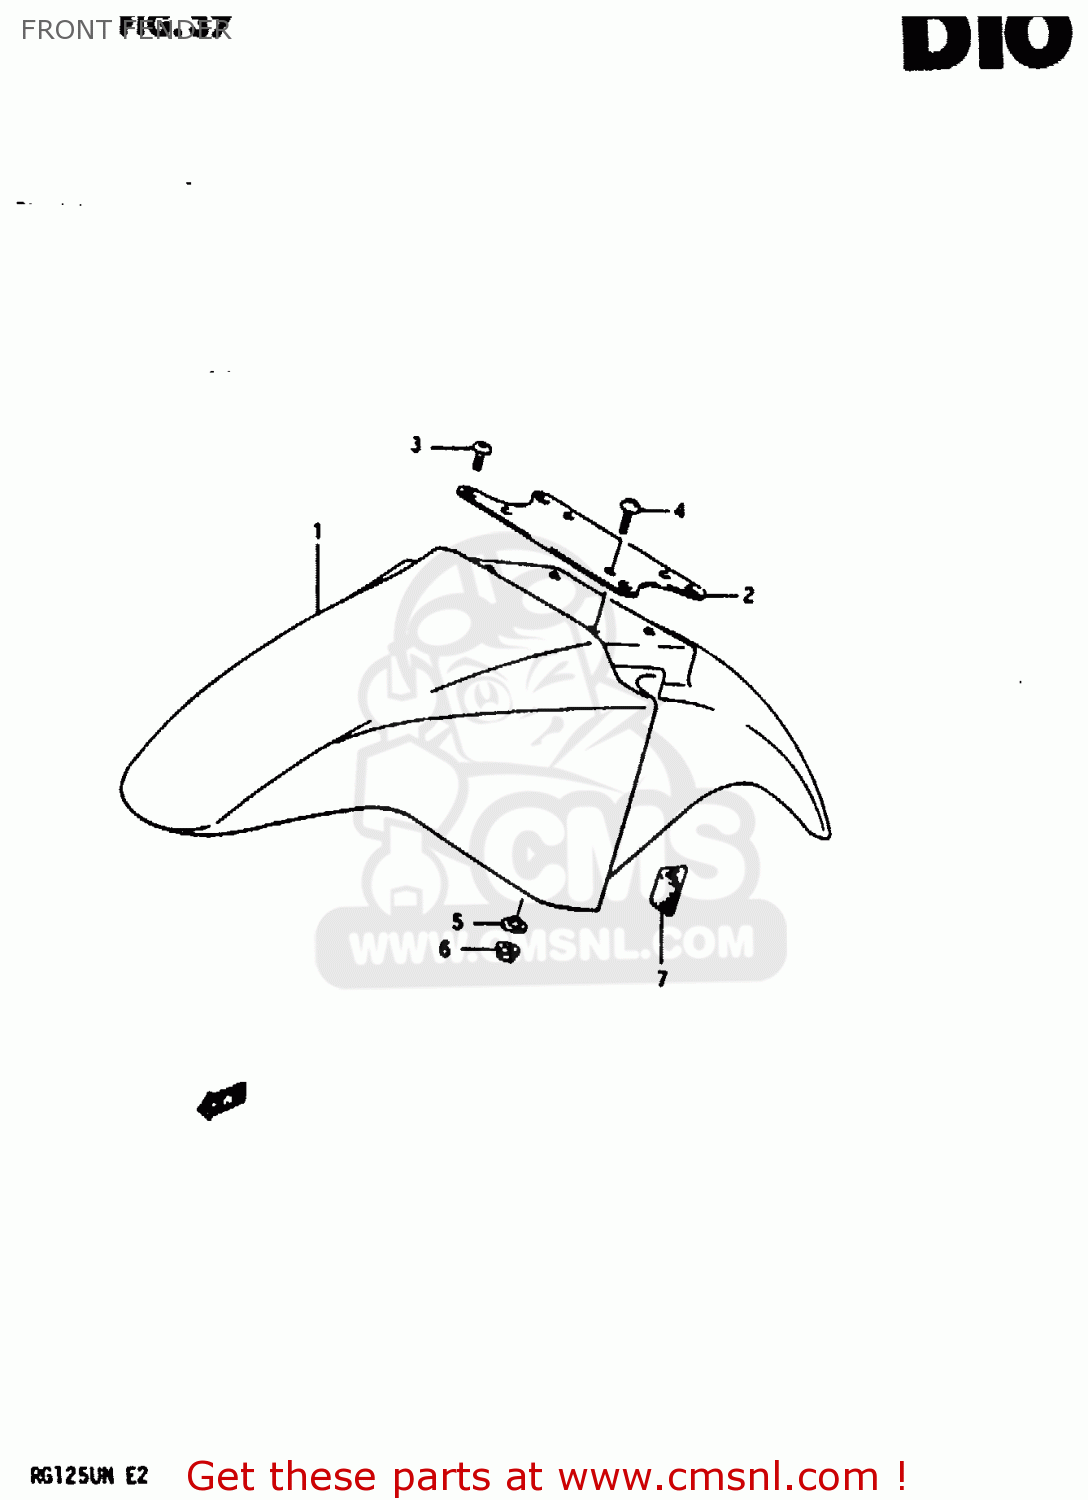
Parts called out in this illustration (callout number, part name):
1	FENDER,FR
2	BRACE,FR FENDER
3	SCREW(6X12)
4	SCREW(5X16)
5	WASHER
6	NUT
7	CUSHION,FRONT FENDER
